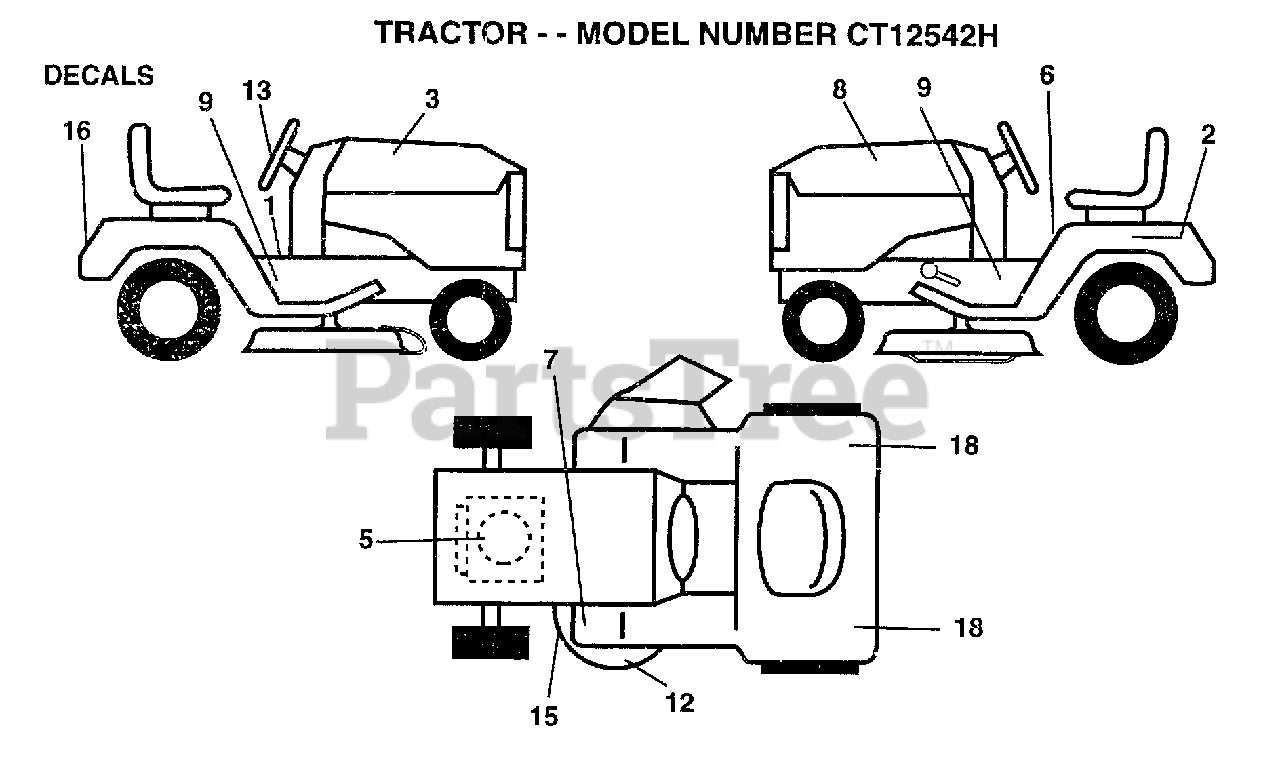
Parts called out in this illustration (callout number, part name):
2	DECAL.BTRY.DANGER
3	DECAL.HD.RH.12.5
5	DECAL, HP ENGINE
6	DECAL
8	DECAL.HD.LH.12.5
9	DECAL.CHAS.42.RAL
13	DECAL.WHL.STR.RLY
15	DECAL
16	DECAL.FEND.RALLY
18	REFLECTOR-TAIL YT
